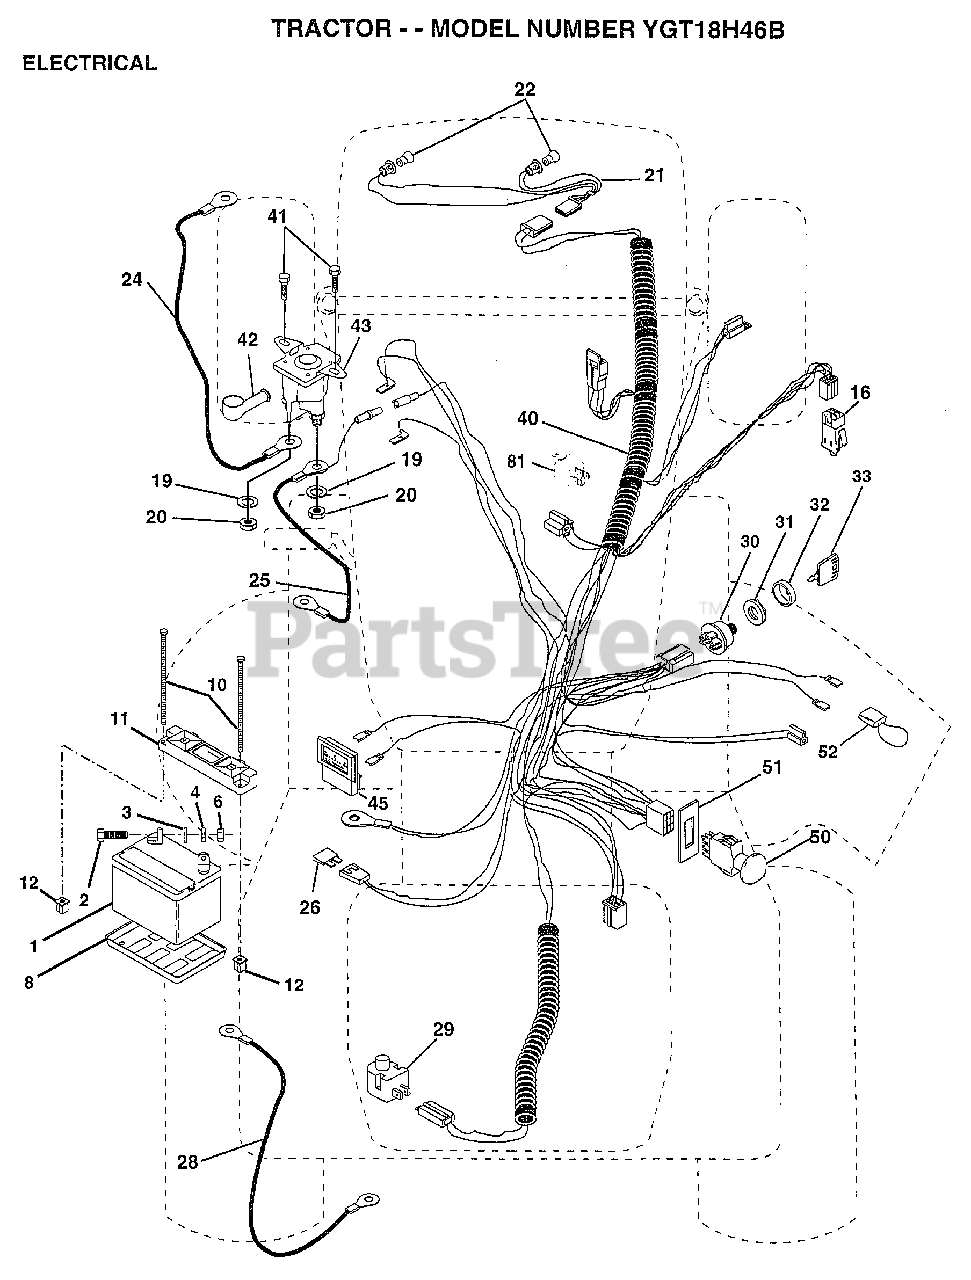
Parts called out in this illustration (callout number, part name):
3	WASHER
4	LOCKWASHER
8	"TRAY T, BATTERY"
11	HOLDDOWN BATTERY
16	SWITCH INTERLOCK
20	NUT
21	"HARNESS,LIGHT SOC"
22	HEADLAMP BULB
24	CABLE.BATY.22.RED
25	CABLE.BATRY.4GA.
26	FUSE HYT
28	"CABLE BATTERY,GRD"
29	SWITCH.PLUNGER
30	SWITCH IGN 4POS
31	NUT IGNITION
32	COVER KEY SWITCH
33	KEY
40	HARNESS.IGN.
41	SCREW
45	AMMETER
50	PTO SWITCH.BLK
51	RING RETAIN PTO
52	PROTECTION LOOP
81	RELAY ASSY T
